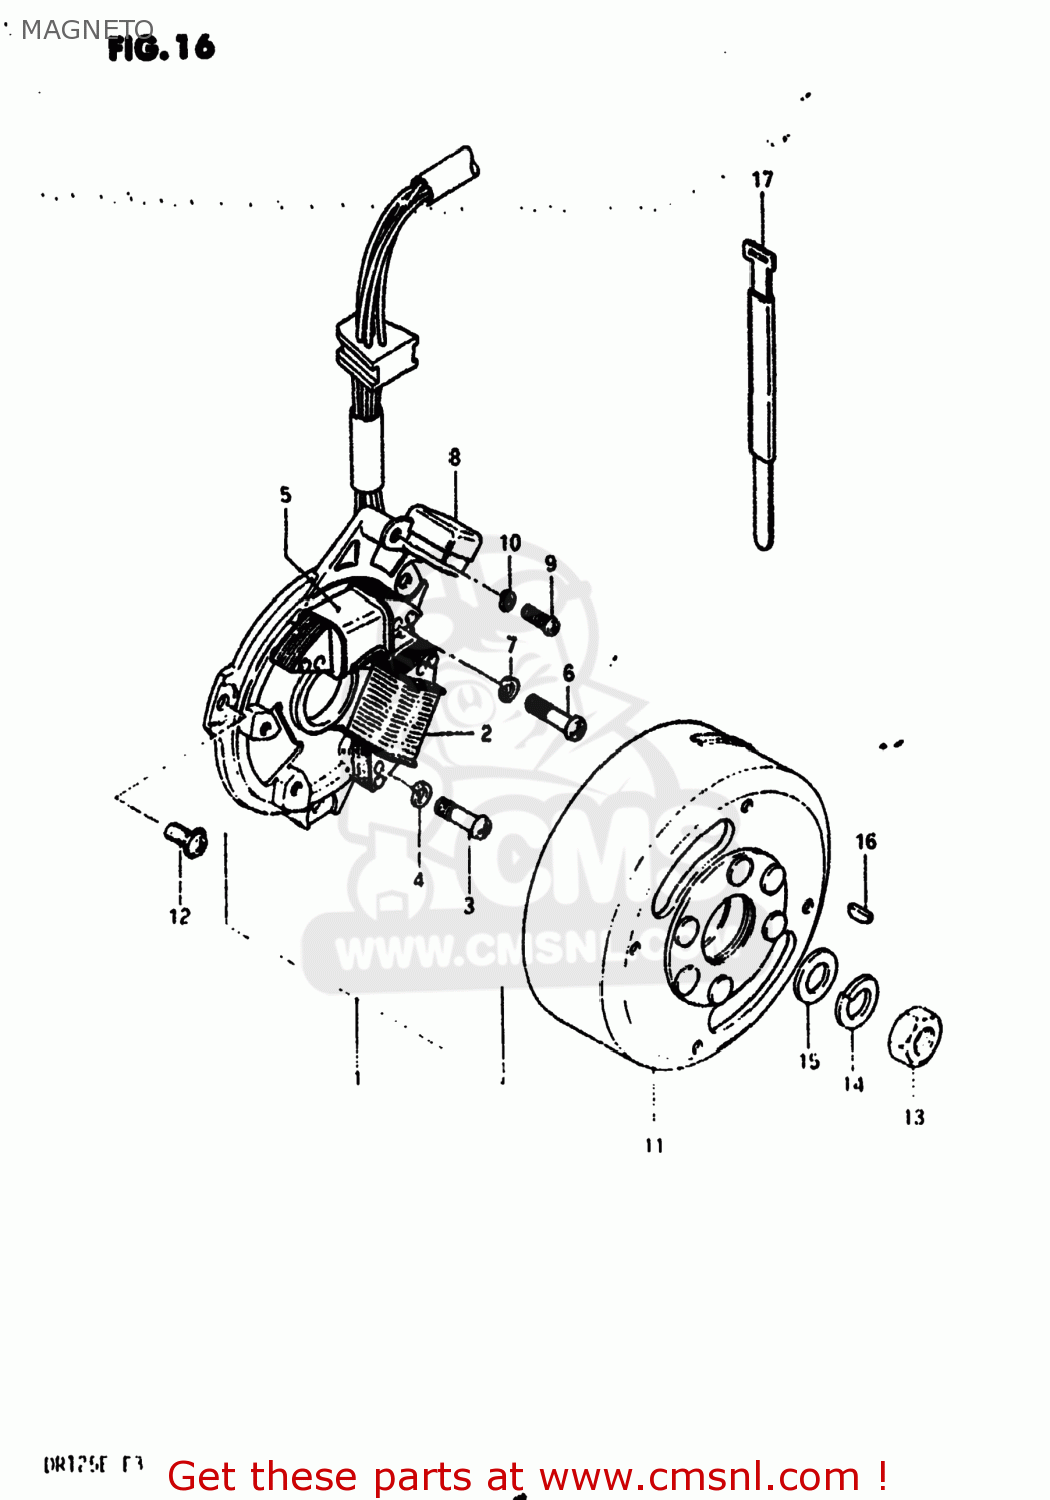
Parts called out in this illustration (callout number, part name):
1	STARTER ASSY
2	COIL,LIGHTING
3	SCREW
4	LOCK WASHER
5	COIL,IGNITION PRIMARY
6	SCREW
7	LOCK WASHER
8	COIL
9	SCREW
10	LOCK WASHER
11	ROTOR ASSEMBLY
12	SCREW(5X14)
13	NUT (10MM)
14	LOCK WASHER
15	WASHER
16	KEY
17	CLAMP L:110
